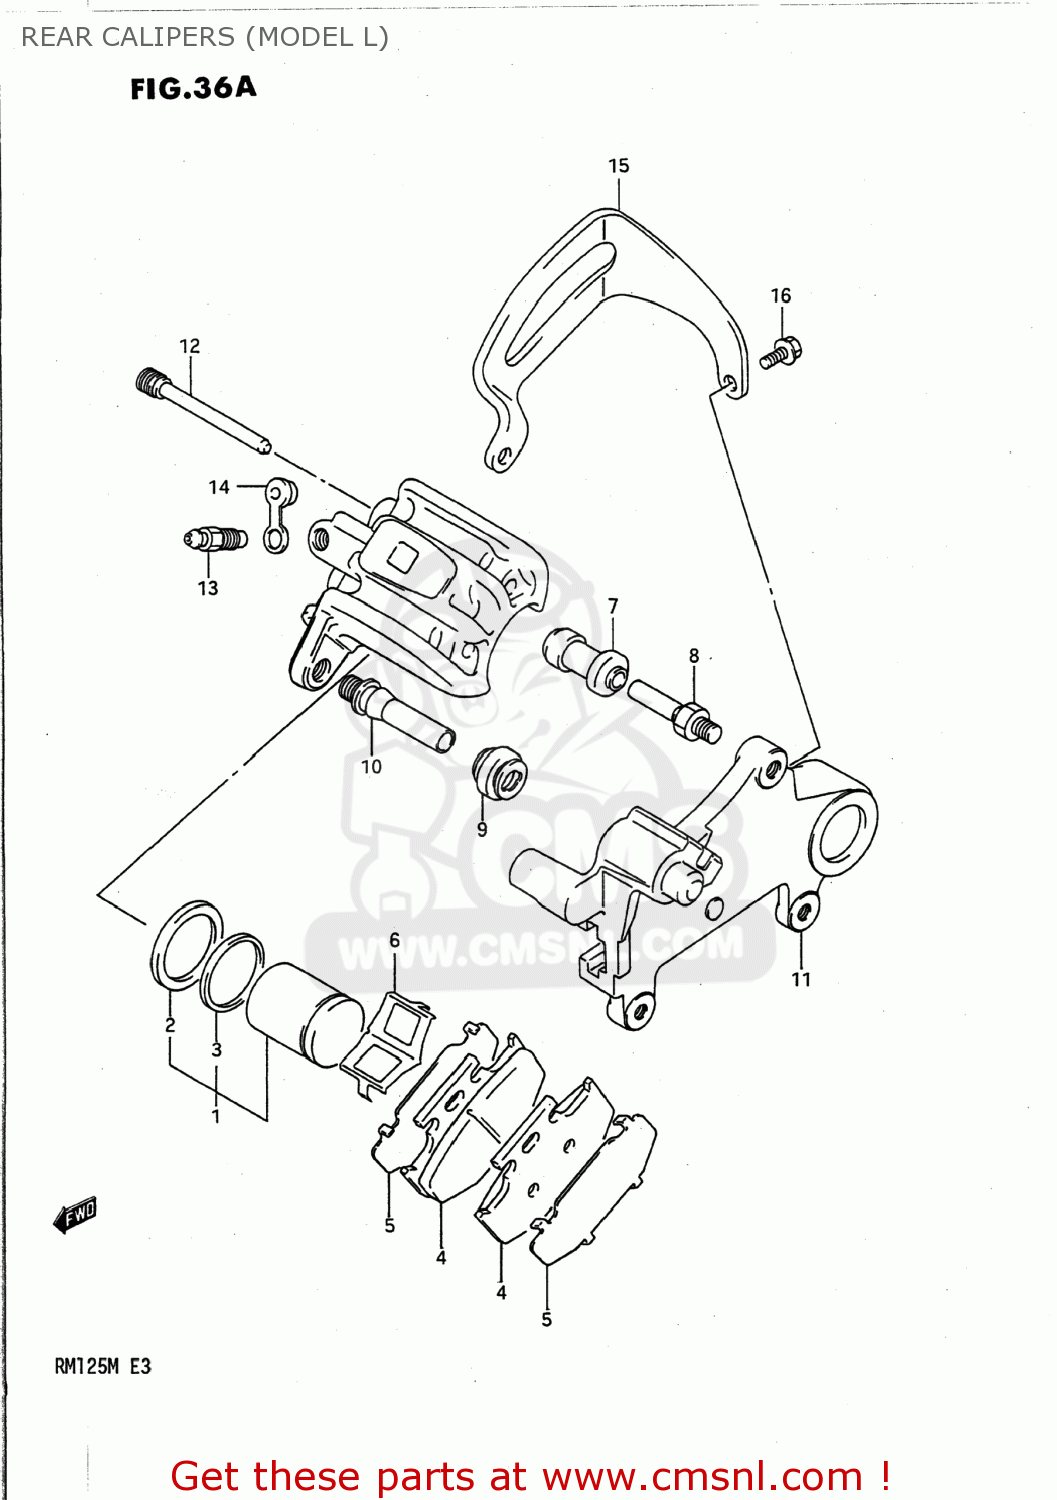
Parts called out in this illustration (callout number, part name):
1	PISTON SET
2	SEAL,PISTON
3	SEAL,DUST
4	PAD
5	SHIM
6	SPRING,PAD
7	BOOT
8	PIN,BOLT
9	BOOT
10	PIN
11	BRACKET
12	PIN,HANGER
13	BLEEDER
14	CAP,BLEEDER
15	GUARD,RR CALIPER
16	BOLT
